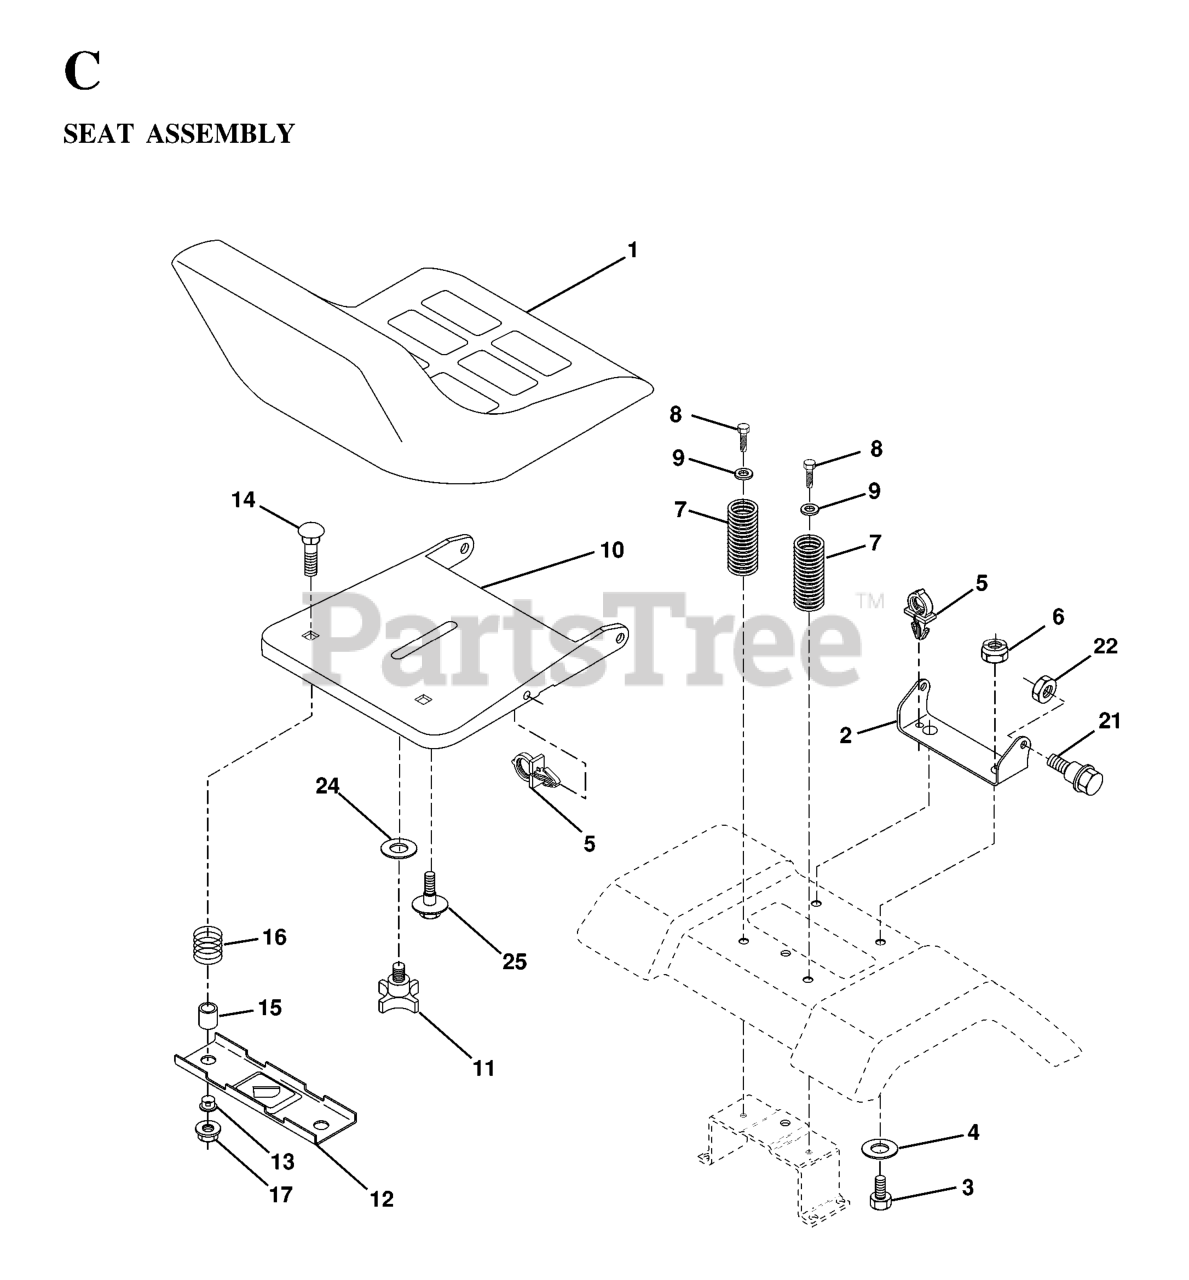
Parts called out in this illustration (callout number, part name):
1	SEAT, GRAY
2	SEAT PIVOT BRKT
3	BOLT
6	NUT
7	SPRING COMPRESSION
8	SCREW GTV
9	WASHER
10	PAN, SEAT
11	KNOB 1/2" YT
12	BRKT SWITCH
14	Bolt Rdhd. Sht. Nk 1/4-20 x 1-3/8
15	SPACER SPLIT 28X.96
17	NUT T
21	BOLT SHOULDER 5/16-18
22	NUT.71038.31-18.HEX.NYLOCK
25	BOLT,SHOULD
